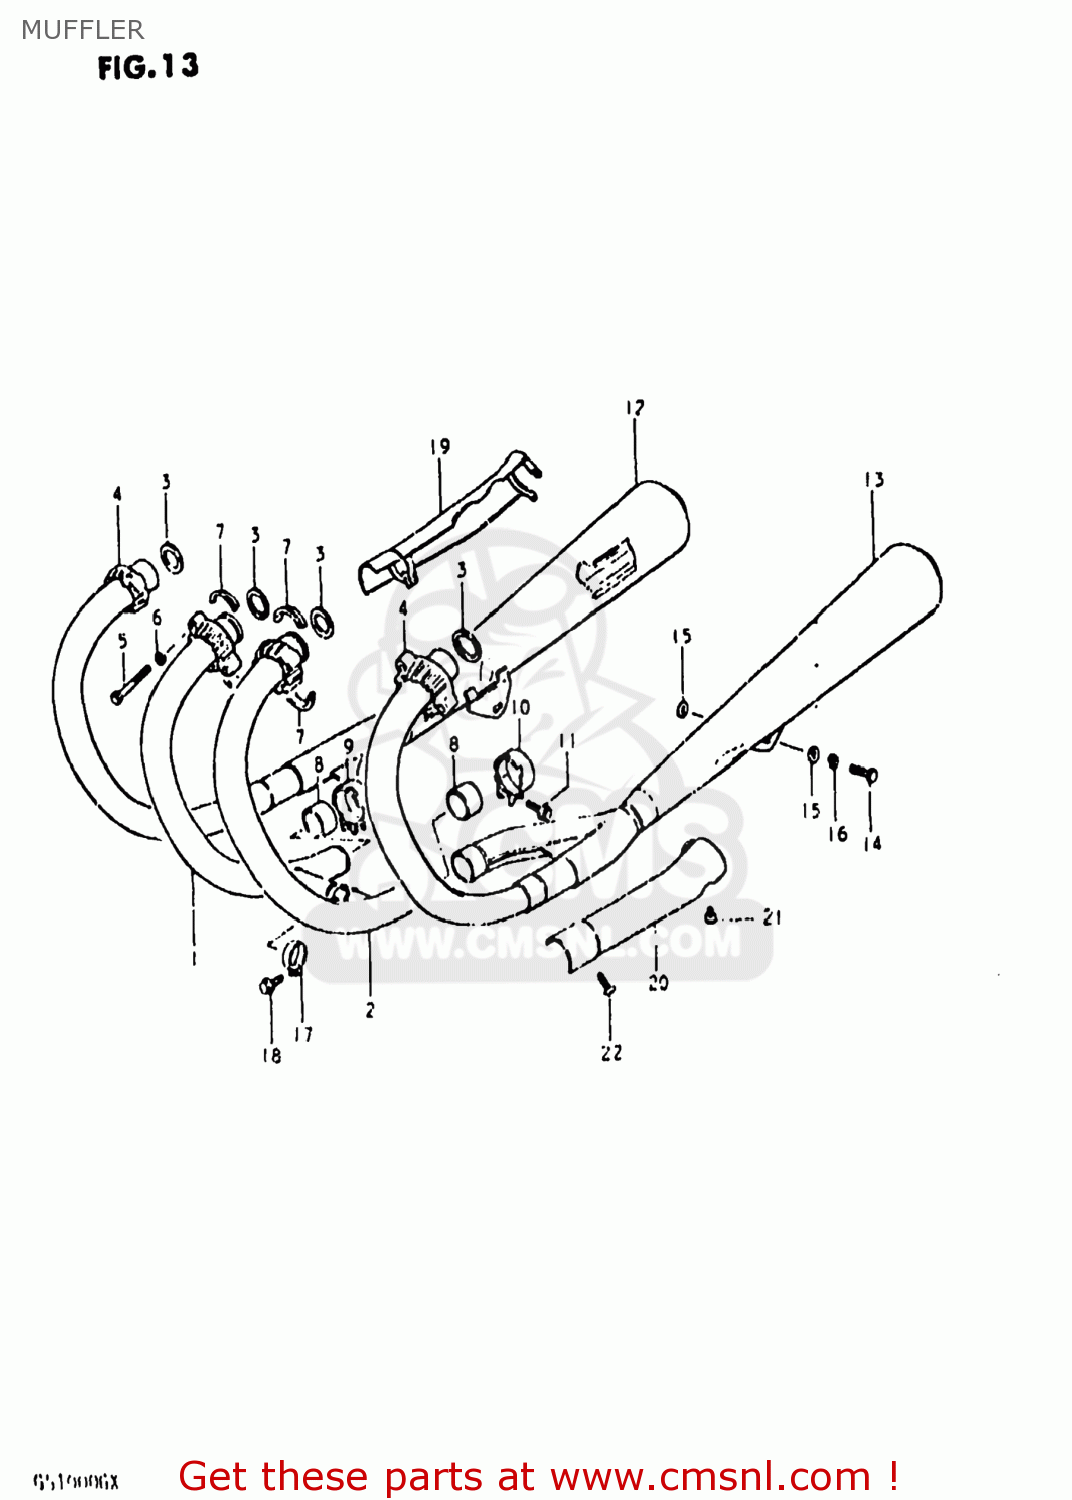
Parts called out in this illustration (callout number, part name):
1	PIPE,CENTER EXHAUST
2	COVER,EXHAUST PIPE
3	GASKET,EXHAUST PIPE (NAS)
4	CLAMP,EXHAUST PIPE
5	BOLT 8X45
6	LOCK WASHER
7	PLATE,EXHAUST
8	CONNECTOR,MUFFLER
9	CLAMP,MUFFLER CONNECTOR,R
10	CLAMP,MUFFLER CONNECTOR,L
11	BOLT
12	BODY,MUFFLER
13	BODY,MUFFLER
14	BOLT 10X30
15	WASHER
16	LOCK WASHER
17	CLAMP
18	BOLT
19	COVER,MUFFLER,R
20	COVER,MUFFLER
21	SCREW
22	SCREW
